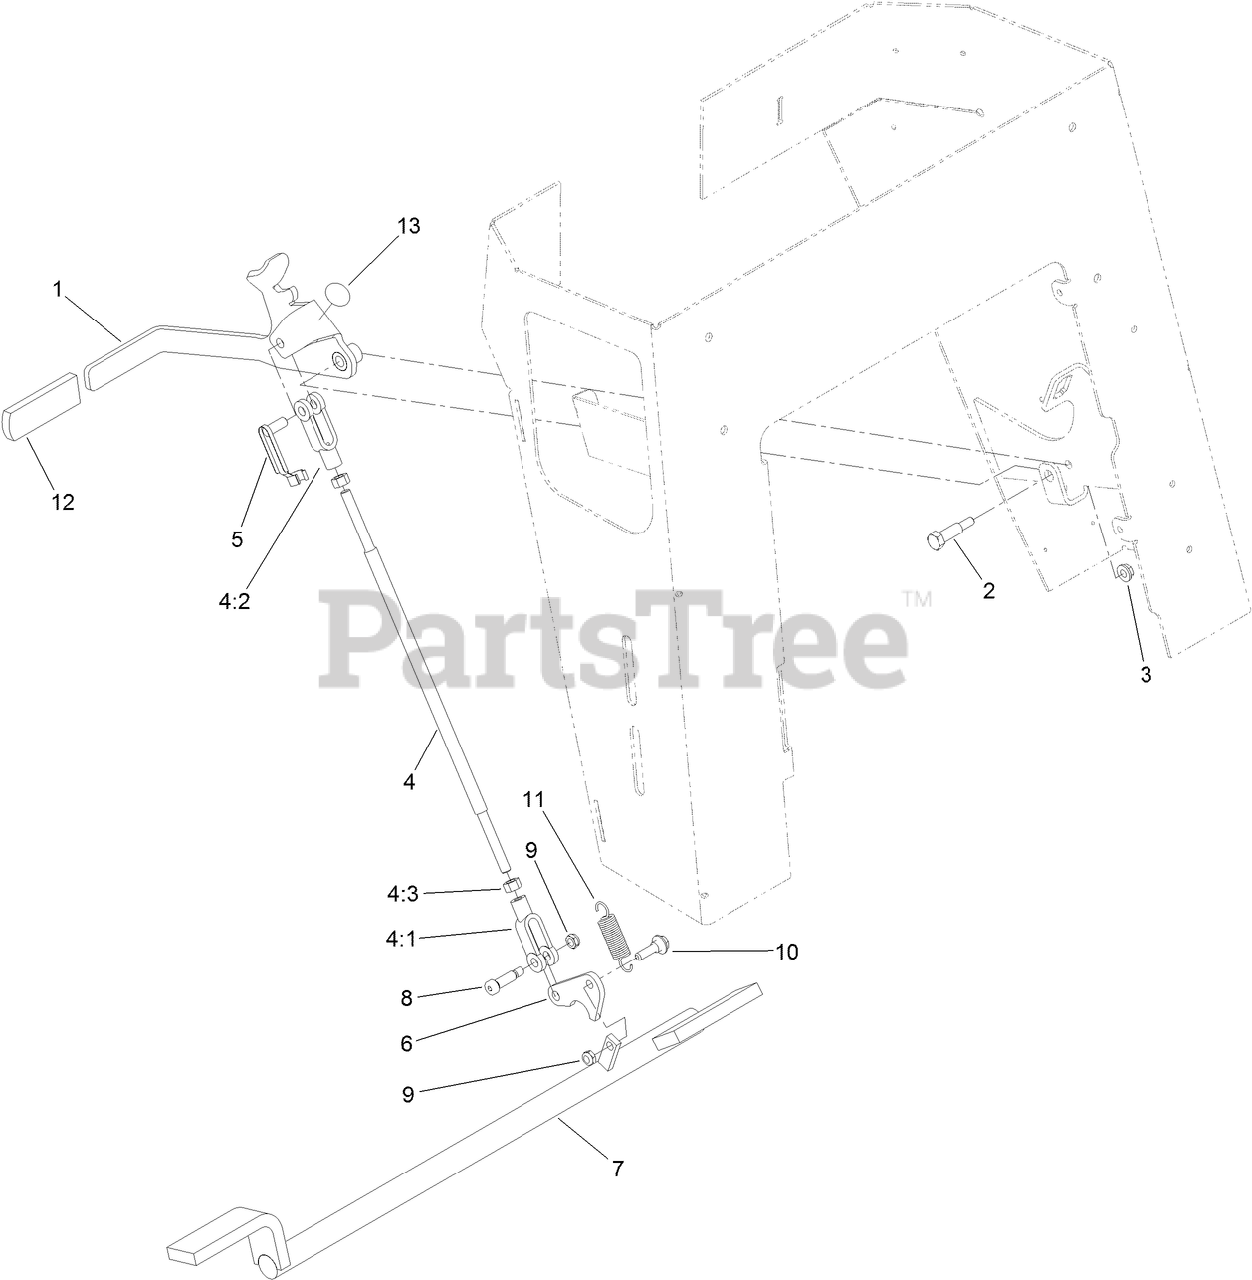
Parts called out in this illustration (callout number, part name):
1	HANDLE-BRAKE
2	SCREW-SHOULDER, HH
3	NUT-HF
4	BRAKE ROD ASM
4:1	YOKE-LINKAGE, BRAKE
4:2	LINKAGE-HANDLE, BRAKE
4:3	NUT-HEX
5	PIN-SPRING, CLEVIS
6	LINK-MOUNTING
7	BAR-BRAKE
8	BOLT-SHOULDER
9	NUT-LOCK, NI
10	SCREW-SHOULDER
11	SPRING-IDLER
12	GRIP-HANDLE
13	DECAL-PARKING BRAKE
